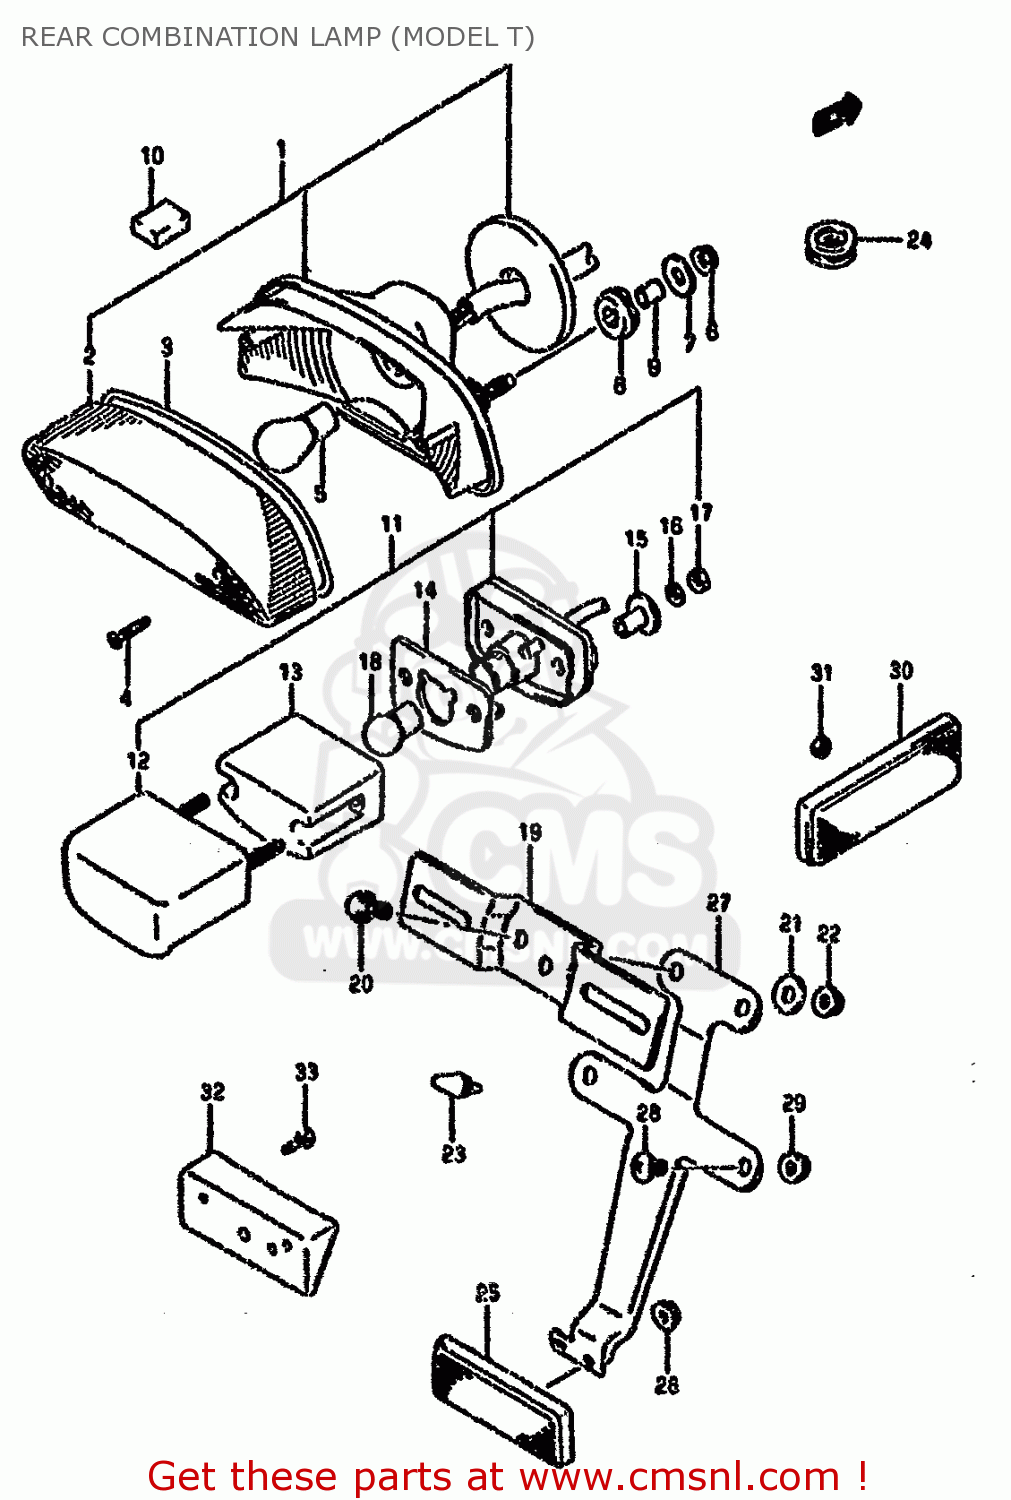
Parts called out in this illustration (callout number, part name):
1	LAMP ASSY,RR COMBINATION
2	LENS
3	GASKET (NAS)
4	SCREW
5	BULB(12V21/5W)
6	NUT
7	WASHER(6.5X20X1.2)
8	CUSHION
9	SPACER (6.1X9X10)
10	CUSHION,REAR COMBINATION LAMP
11	LAMP ASSY,LICENCE
12	COVER,LICENSE LAMP
13	LENS
14	GASKET,LICENSE LAMP (NAS)
15	SPACER
16	WASHER,LOCK
17	NUT
18	BULB(12V5W,BF150-40160A)
19	BRACKET,LICENSE PLATE
20	BOLT
21	WASHER(6.5X20X1.6)
22	NUT
23	CUSHION
24	GROMMET
25	REFLECTOR ASSEMBLY,REAR
26	NUT
27	BRACKET,RR RR
28	SCREW 6X12
29	NUT
30	REFLEX REFLECTOR,FR SIDE
31	NUT
32	SPACER,RR RR
33	SCREW
34	WASHER
